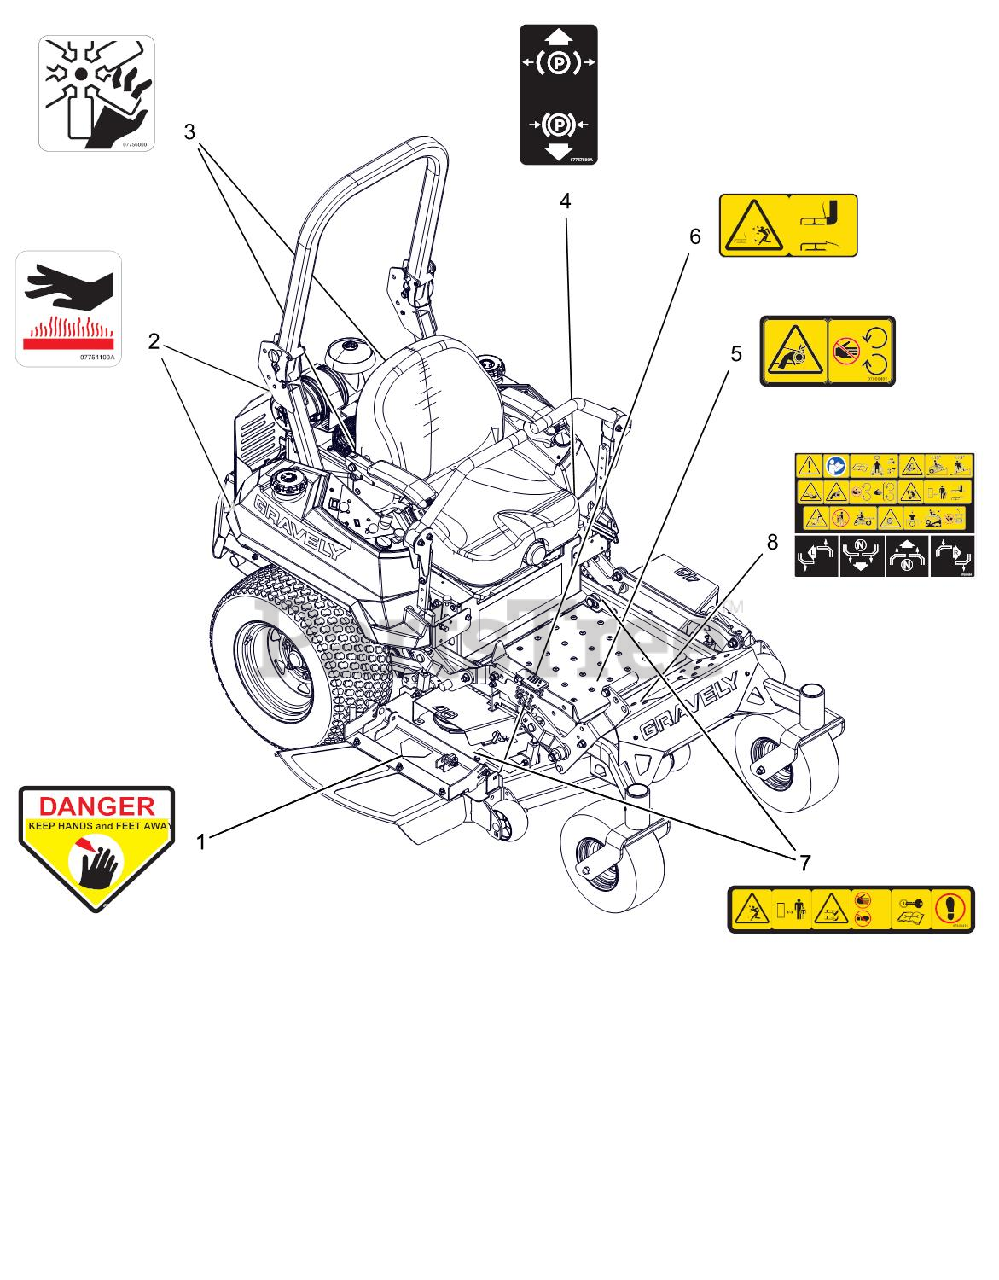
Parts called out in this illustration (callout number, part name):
1	DECAL, DANGER
2	DECAL, HOT SURFACE
3	DECAL, DANGER FAN
4	DECAL, PARKING BRAKE LEVER
5	DECAL, SAFETY - GUARDING
6	DECAL, SAFETY - DECK GUARDING
7	DECAL, DECK SAFETY
8	DECAL, INSTR SAFETY
